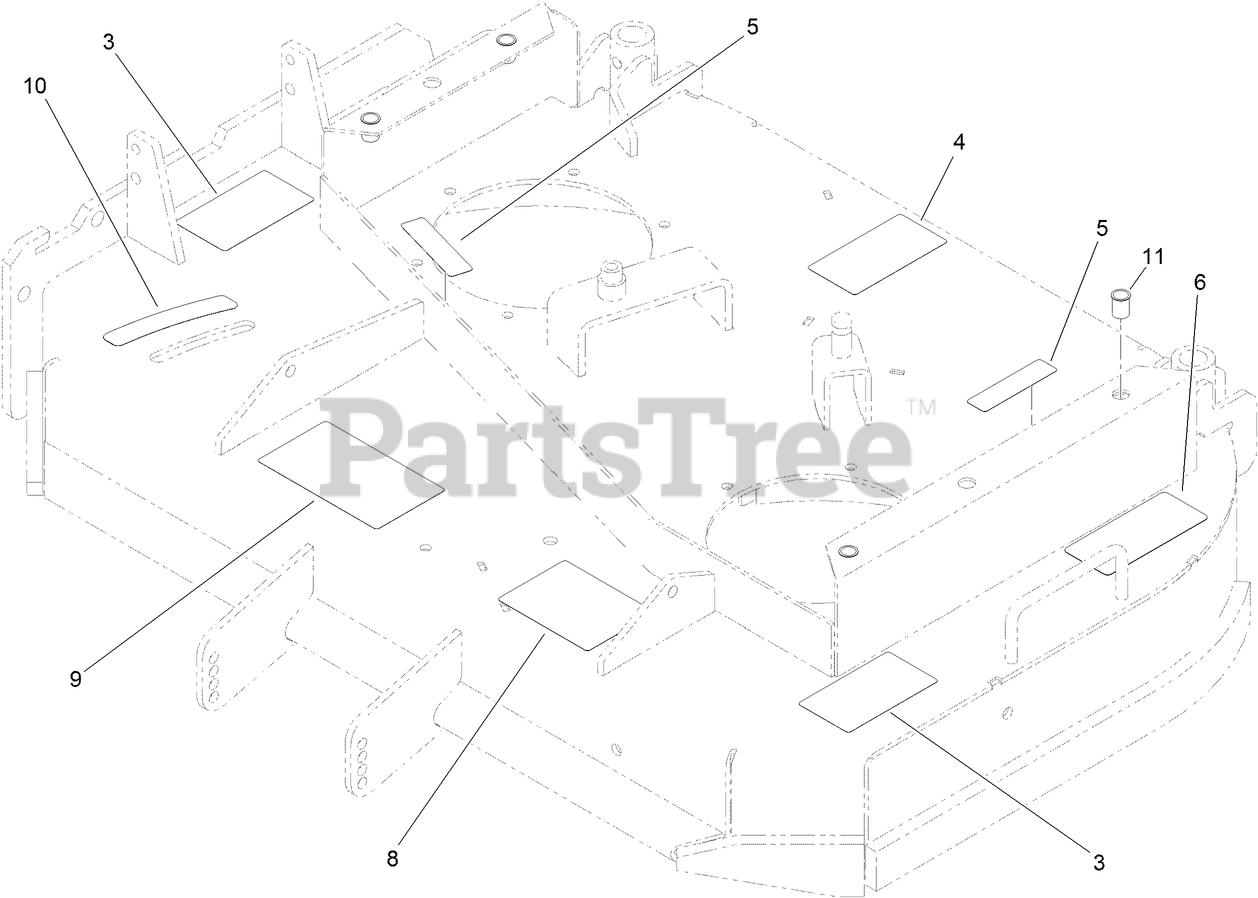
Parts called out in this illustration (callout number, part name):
3	DECAL-DANGER
5	DECAL-DANGER
6	DECAL-TORQUE, BLADE BOLT
8	DECAL-ANTI SCALP
9	DECAL-ADJUSTMENT, BAFFLE
10	DECAL-SETTING, BAFFLE
11	INSERT-NUT
